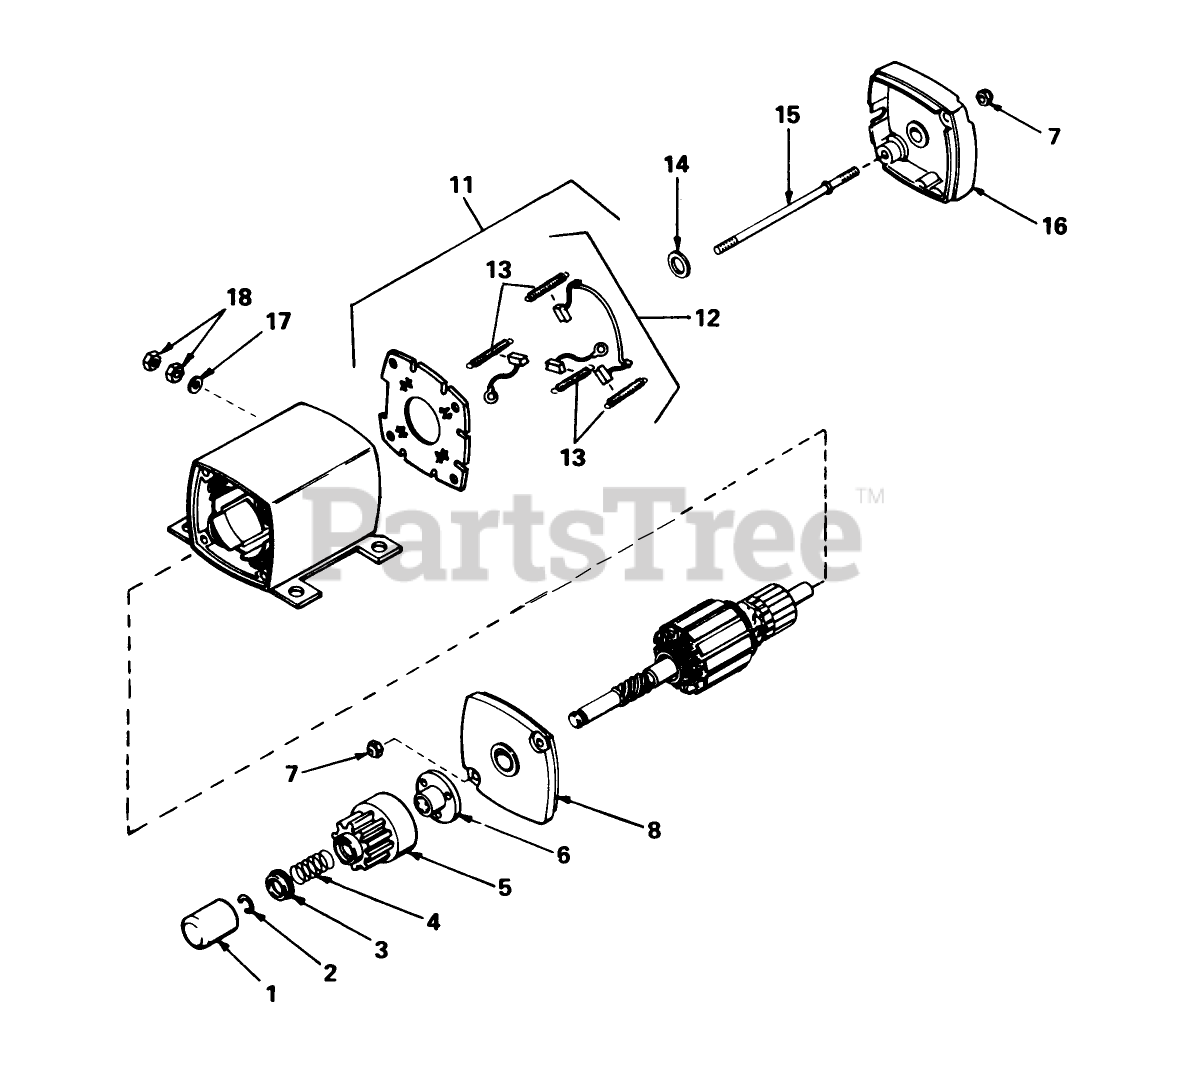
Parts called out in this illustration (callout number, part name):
1	Cover-Dust
2	Ring-Retainer
3	Retainer-Spring
4	Spring-Anti Drift
5	Gear
6	Nut-Engaging
7	Nut-Lock
8	Cap Assy., Drive End
11	Card Assy., Brush (Incl. No. 12)
12	Brush Spring Kit (Incl. 4 pcs. of #13)
13	1545D SUP TO W/3256
14	Washer-Thrust
15	Bolt
16	2035A67 WIZARD W/34
17	Washer
18	Nut-Hex
